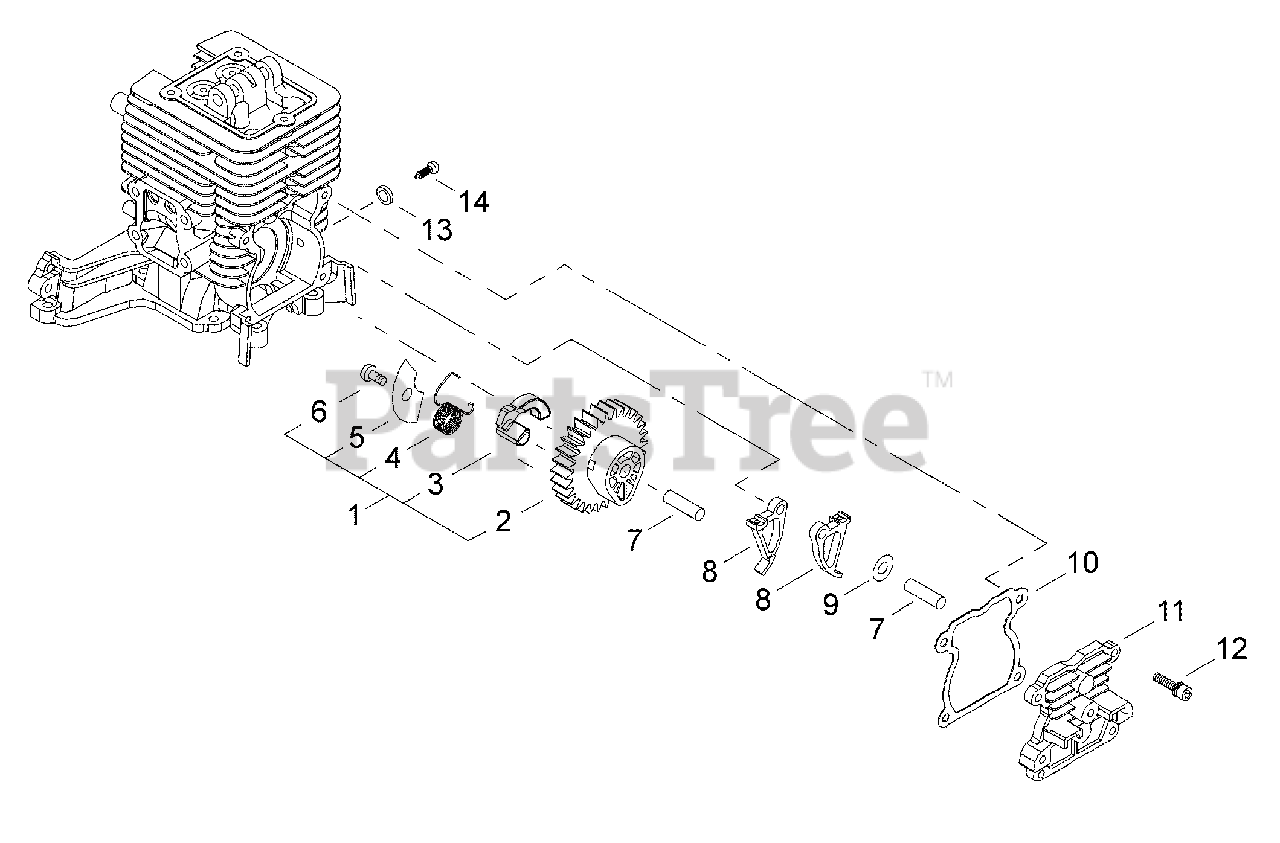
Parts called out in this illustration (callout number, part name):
1	CAM GEAR ASSY
2	GEAR, CAM
3	WEIGHT
4	SPRING
5	COVER, PLATE
6	SCREW - 4X6 -- TAPPING
7	PIN - LOCATING
8	FOLLOWER, CAM
9	WASHER - 5
10	GASKET
11	COVER, CAM GEAR
12	SCREW - 4X14
13	WASHER
14	SCREW - 5
